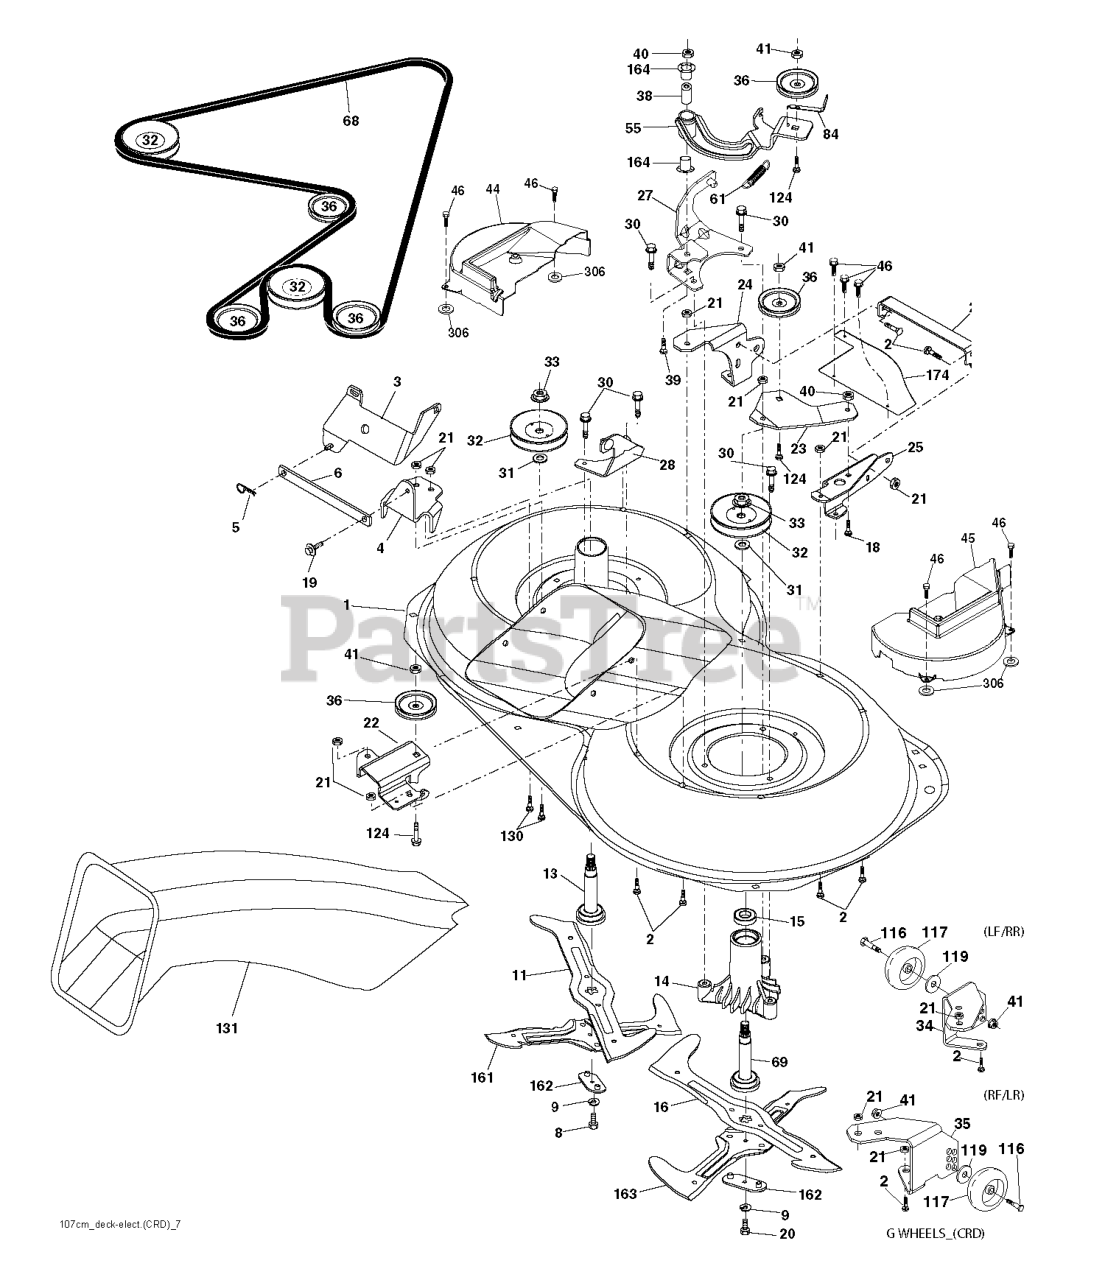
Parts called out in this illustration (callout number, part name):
1	Housing Asm. Mower 107 CRD
2	RP BOLT 5/16-18 X3/4 ZN/YEL GR
5	RETAINER-SPRNG RB
6	BAR.SWAY.92.CRD
8	BOLT.3/8-24X1.25 GR8
9	LOCKWASHER
11	BLADE.3N1.LH.CRD
13	SHAFT ASM VENT
14	HOUSING.MANDREL.VENTED (MACHD)
16	BLADE.3N1.RH.CRD
19	BOLT SHD 5/16-18
20	BOLT.3/8-24X1.25GR8. LHTHRD
21	LOCKNUT
22	BRACKET.IDLER.RR.107.CRD
24	BRACKET
25	BRACKET RF
26	SUPPORT
28	BRACKET
30	SCREW, WASHER HEAD
31	WASHER.SPACER.MANDREL
32	PULLEY.MANDREL.4.80 PD.2006
33	NUT.FLANGE.LOCK.TOP
34	BRACKET
35	BRACKET
36	PULLEY.IDLER.4.25
41	NUT LOCK FLG 3/8-16 UNC
46	SCREW.1/4-20X5/8
55	ARM.IDLER.107.CRD
61	SPRING
68	HEX-BELT 107 MOWER
69	SHAFT.ASM.W/LWR.BRG.RH.THREAD
84	KEEPER, BELT IDLER
116	BOLT.SHOULDER.3/8-16X3-5/8.
117	RP WHEEL. GUAGE RALLY
119	WASHER
124	BOLT.3/8-16X1.50
130	BOLT.CARR.SQNK.5/16-18UNC.X3/4
131	CHUTE BAGGER
163	BLADE.CROSS.RH.CRD.107
164	BRNG T
174	PLATE
306	PALNUT 1/4
